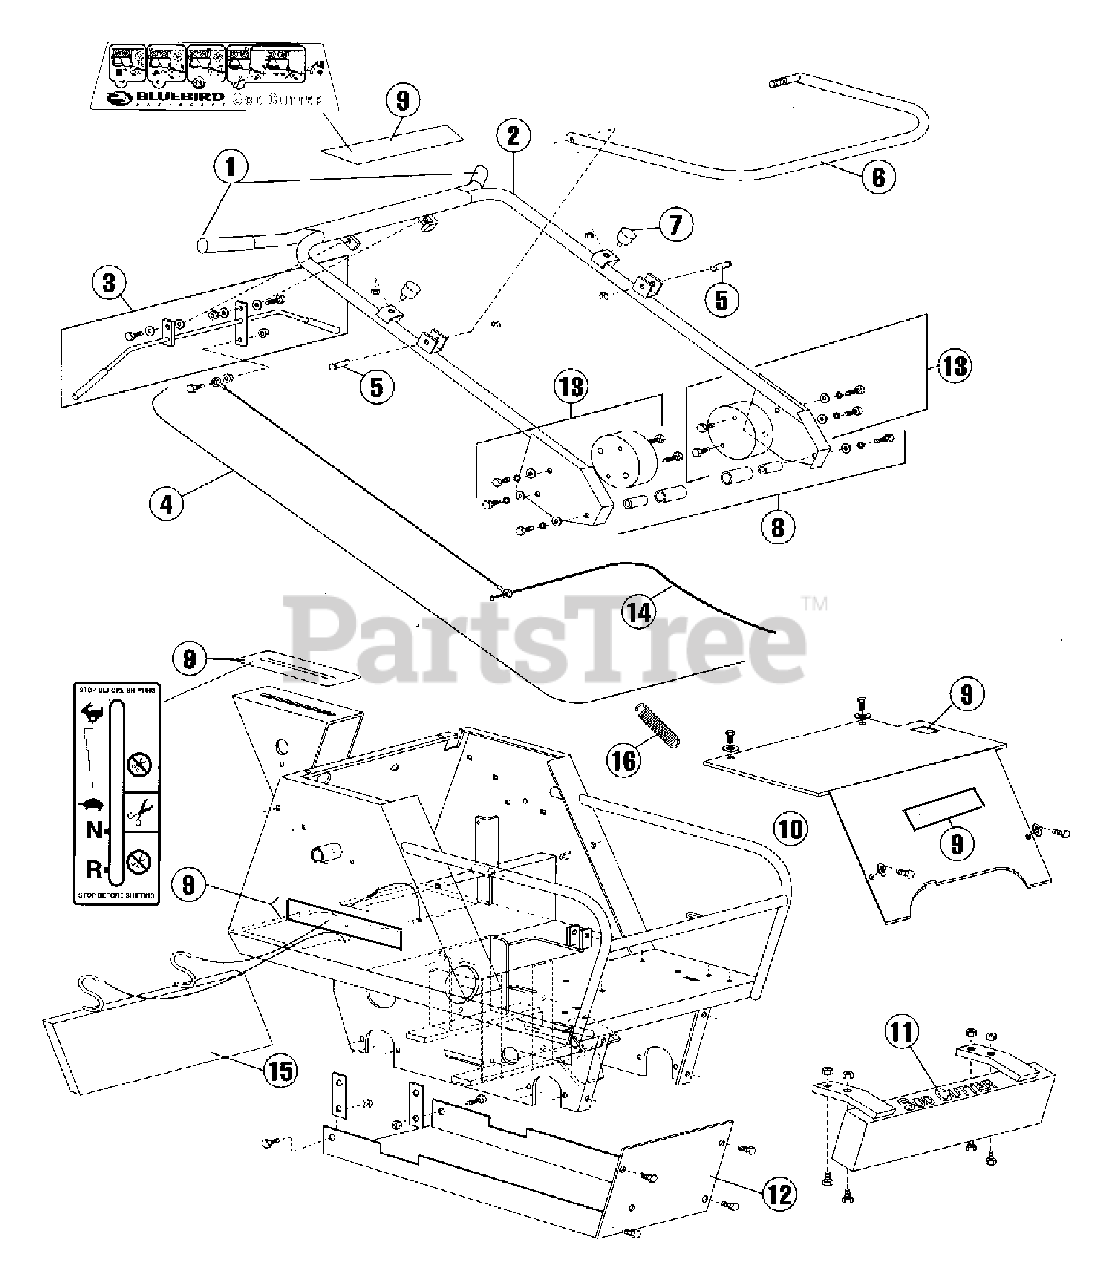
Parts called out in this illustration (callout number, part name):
1	Grips pair
2	Handle kit, complete with grips and hardware
3	Clutch/throttle control kit, with grips and hardware
4	Cable, throttle cable kit
5	Pins, depth handle with clip
6	Blade engagement lever
7	Bumpers, handle (complete)
8	Decal kit, SC18
9	Stand off kit
10	Shield cover kit, upper housing with hardware
11	Weight weldment with hardware
12	Skid pan, complete w/brackets and mounting hardware, deflector
13	Handle attachment hardware kit complete
14	Throttle cable, carb
15	Deflector with "S" links
16	Spring
